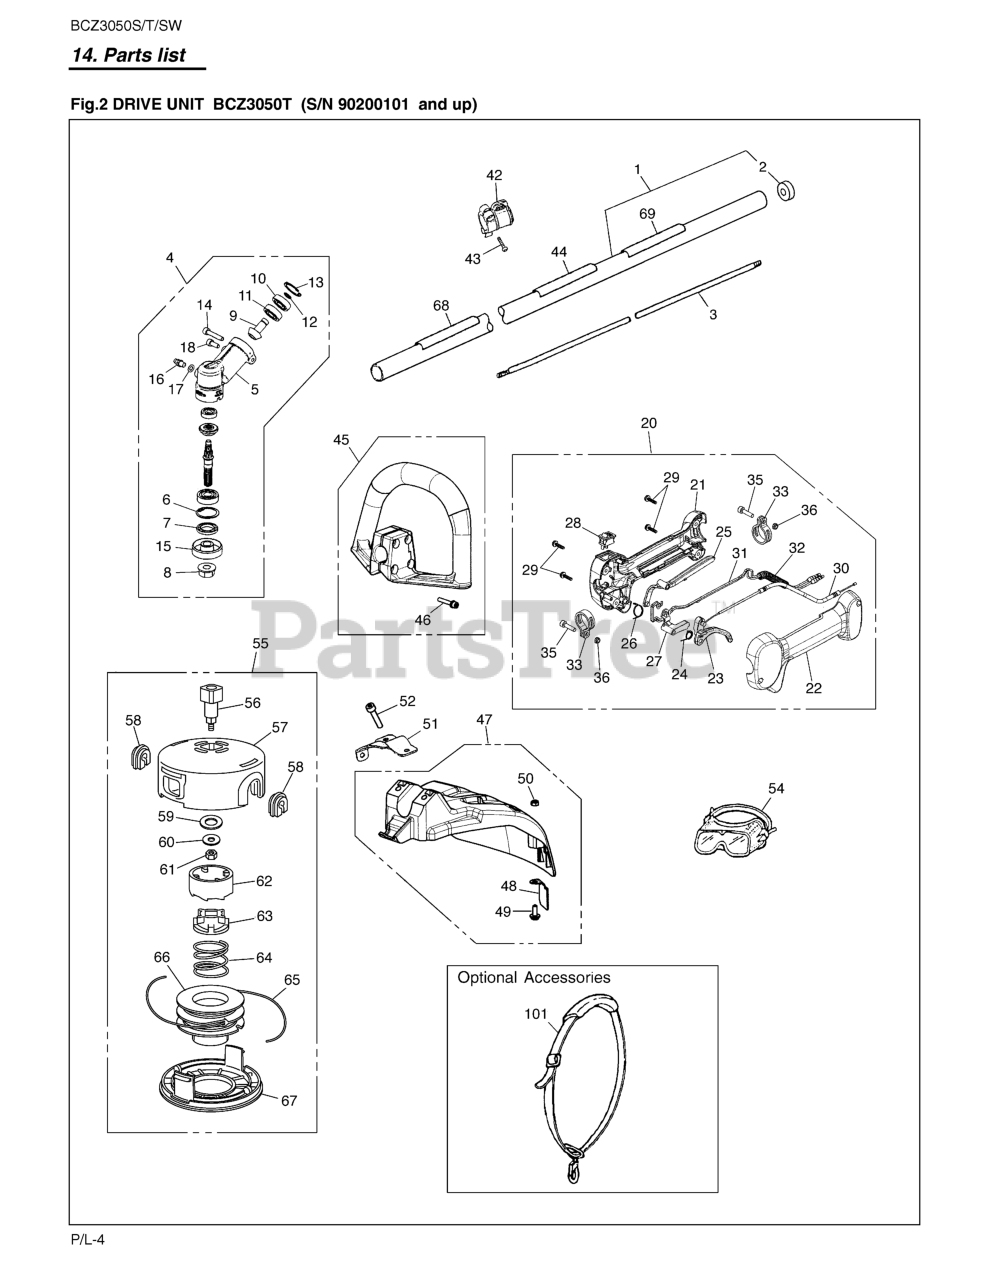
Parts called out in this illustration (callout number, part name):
1	PIPE COMP.
2	SEAL
3	SHAFT
4	GEARCASE ASSY
6	SNAP RING
7	SEAL
8	NUT
10	BEARING
11	BEARING
12	SNAP RING
13	SNAP RING
14	BOLT, TORX
15	HOLDER (A)
16	FITTING, GREASE
17	WASHER, FITTING
18	BOLT
20	GRIP ASSY
23	LEVER, THROTTLE
24	SPRING, THROTTLE
25	LEVER, SAFETY
27	LEVER, JOINT
28	SWITCH
29	SCREW
30	CABLE COMP
31	CORD COMP
32	TUBE
35	BOLT TORX
42	HANGER COMP.
43	SCREW
44	NAME PLATE
45	HANDLE ASSY
46	SCREW
47	GUARD COMP.
48	BLADE
49	SCREW TORX
50	NUT
51	BRACKET
52	BOLT, TORX
54	GOGGLE
55	TAP HEAD COMP
56	ARBOR BOLT
57	CASE
58	EYELET
59	WASHER
60	WASHER
61	NUT
62	HOLDER
63	RATCHET
64	SPRING
66	CORD HOLDER
67	COVER
68	LABEL, CAUTION
69	CAUTION LABEL
101	STRAP ASSY
